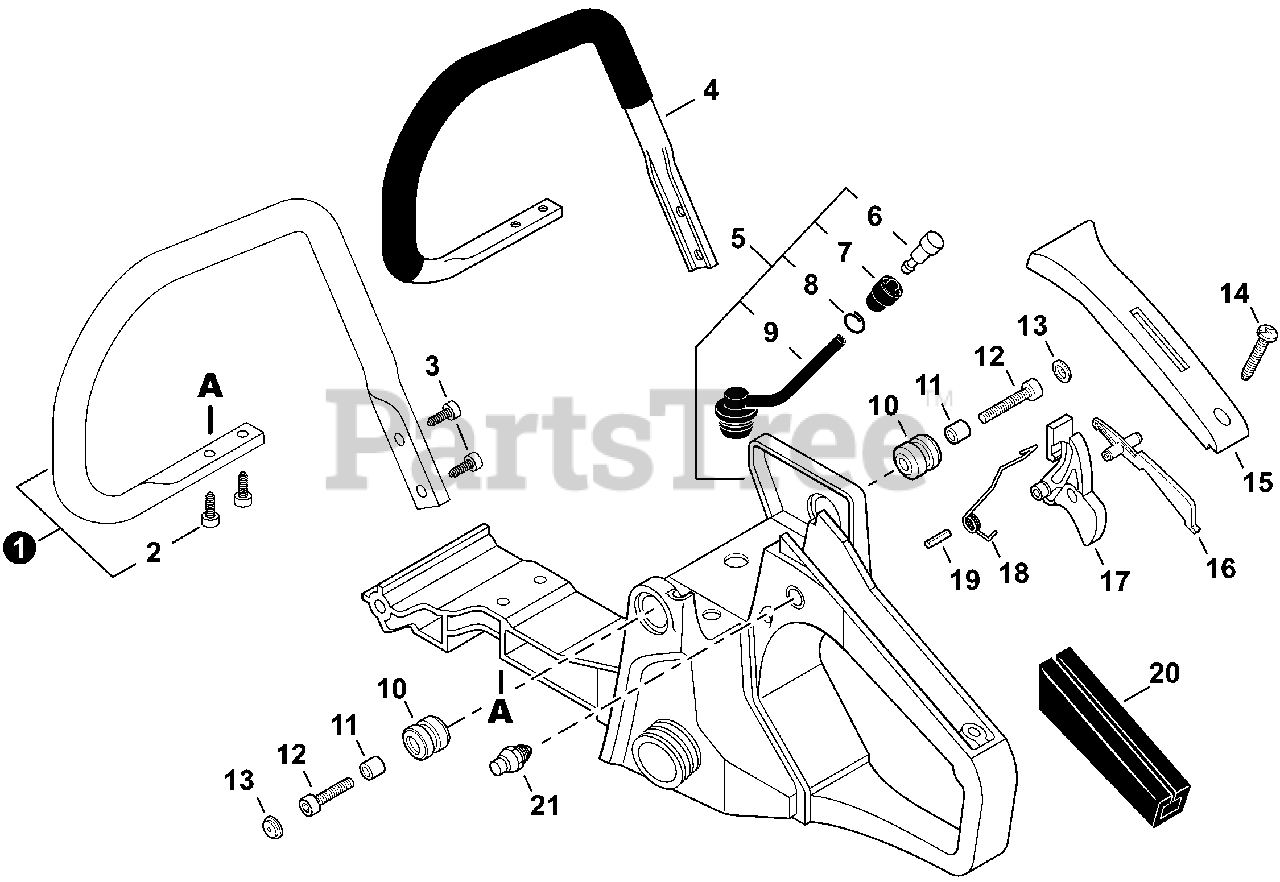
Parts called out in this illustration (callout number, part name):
1	HANDLE SET, FRONT - NYLON
2	SCREW TAPPING 5×20
3	SCREW TAPPING 5×20
4	HANDLE, FRONT - ALUMINUM
5	HANDLE ASSY, REAR
6	VENT ASSY
7	HOLDER, VENT
8	CLIP 6.5 MM
9	PIPE, VENT 3×6×65
10	CUSHION 4
11	COLLAR 4
12	BOLT 4×22
13	CAP, CUSHION
14	SCREW 4×14
15	COVER, HANDLE
16	LOCKOUT, THROTTLE
17	TRIGGER, THROTTLE
18	SPRING, TORSION
19	PIN, SPRING 4×30
20	GRIP, HANDLE
21	LOCK, THROTTLE TRIGGER
